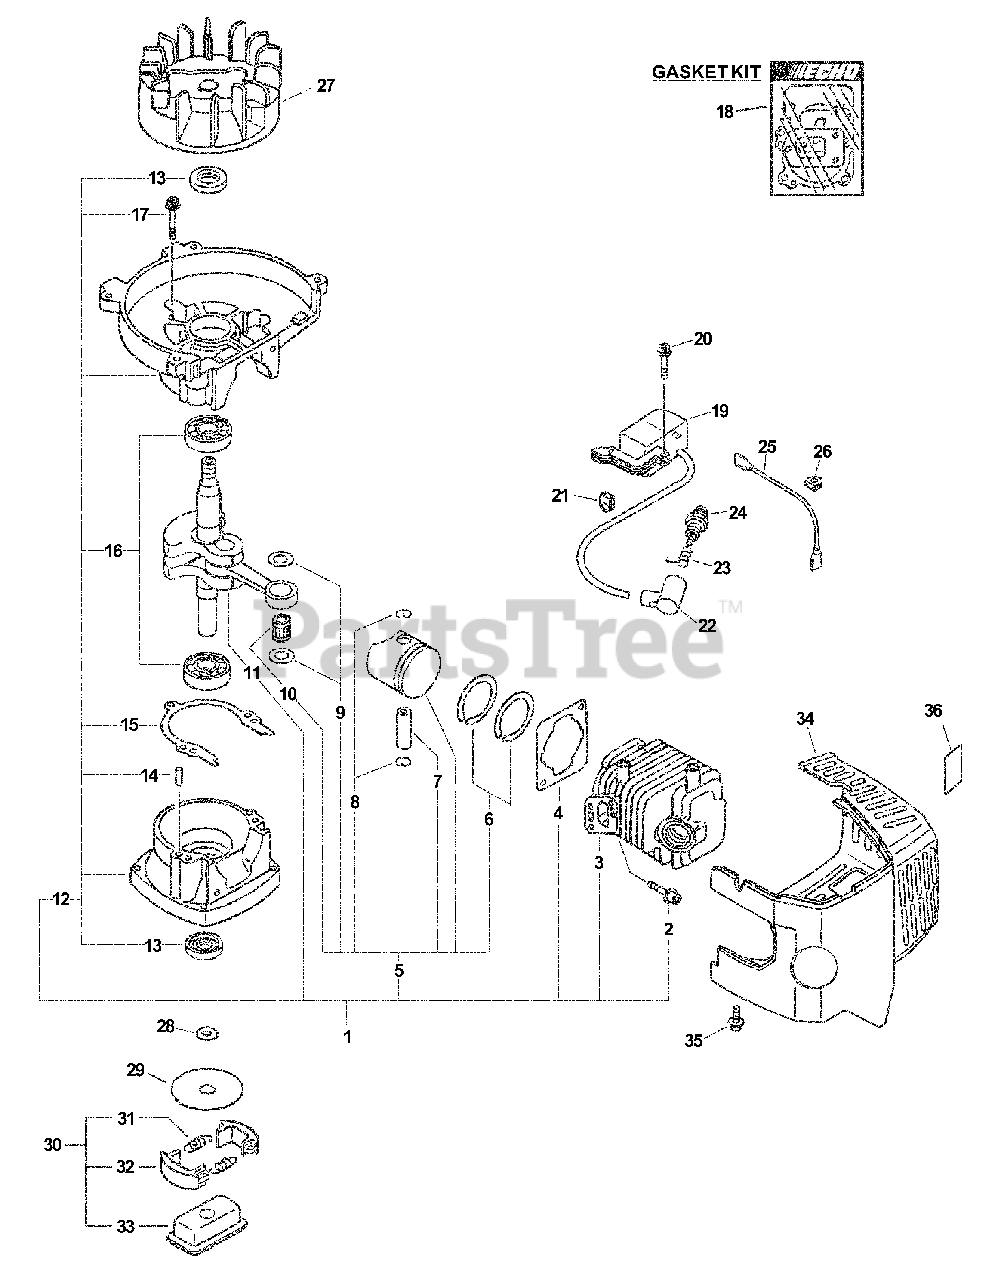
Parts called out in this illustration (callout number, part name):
1	SHORT BLOCK -- SB1050
2	SCREW - 5X22
3	CYLINDER
4	GASKET, CYLINDER
5	PISTON KIT
6	RING, PISTON
7	PIN, PISTON
8	RING, RETAINING
10	BEARING, NEEDLE - 8
11	CRANKSHAFT ASSY
12	CRANKCASE KIT
13	SEAL, OIL
14	PIN - LOCATING
15	GASKET, CRANKCASE
16	BEARING, BALL - 6201
17	SCREW - 5X28
18	GASKET KIT
19	COIL, IGNITION
20	SCREW - 4X22
22	CAP, SPARK PLUG
23	TERMINAL, SPARK PLUG CAP
24	SPARK PLUG -- BPM-7Y
25	LEAD - IGNITION
27	FLYWHEEL
28	WASHER, CLUTCH
29	PLATE, CLUTCH
30	CLUTCH ASSY
31	SPRING, CLUTCH
32	SHOE, CLUTCH
33	HUB, CLUTCH
34	COVER, ENGINE
35	SCREW - 4X20
36	LABEL - HOT SURFACE
